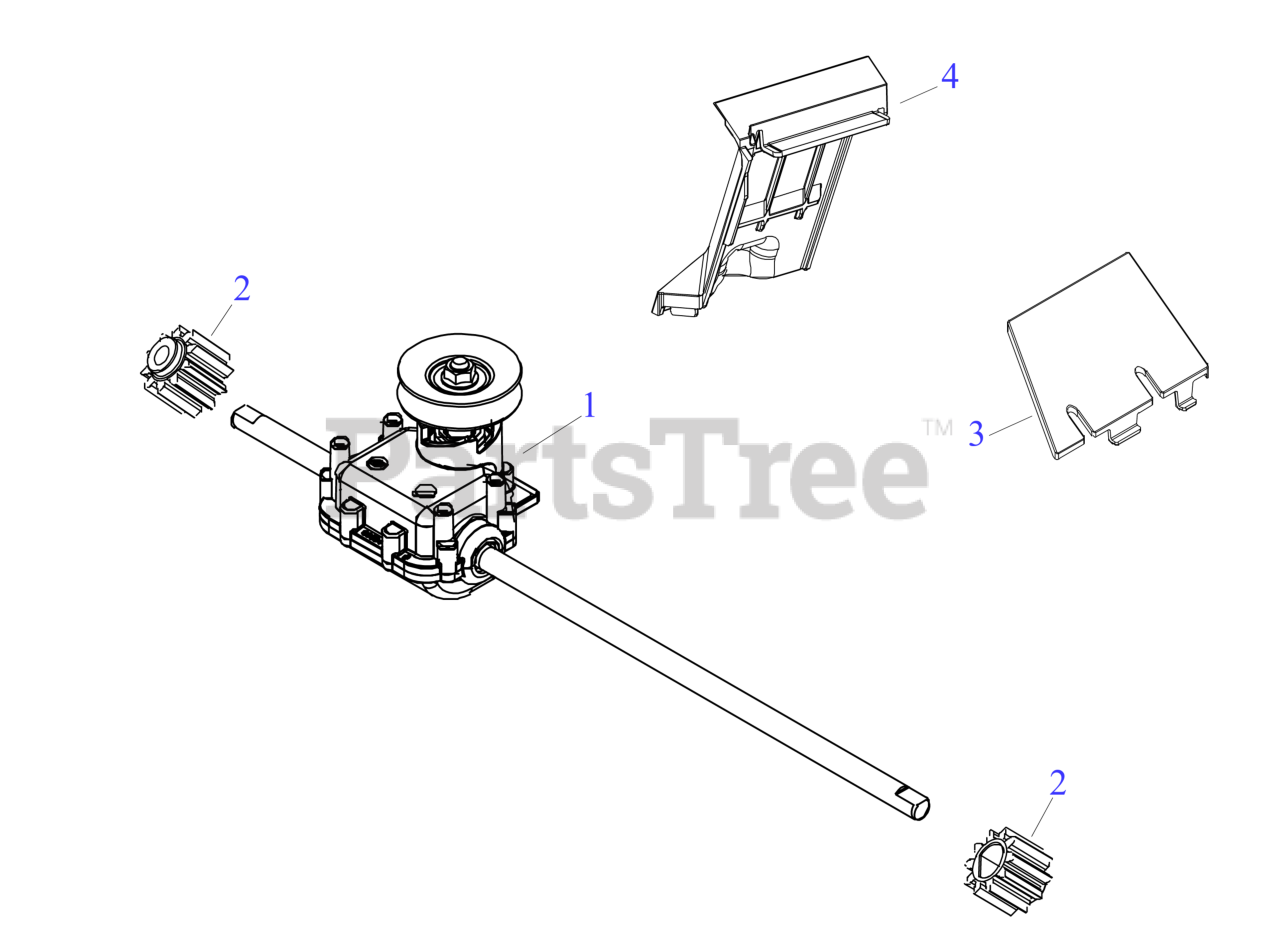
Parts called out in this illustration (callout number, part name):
1	TRANSMISSION
2	SPUR GEAR 9T
3	TRANSMISSION COVER (REAR)
4	TRANSMISSION COVER (REAR)
